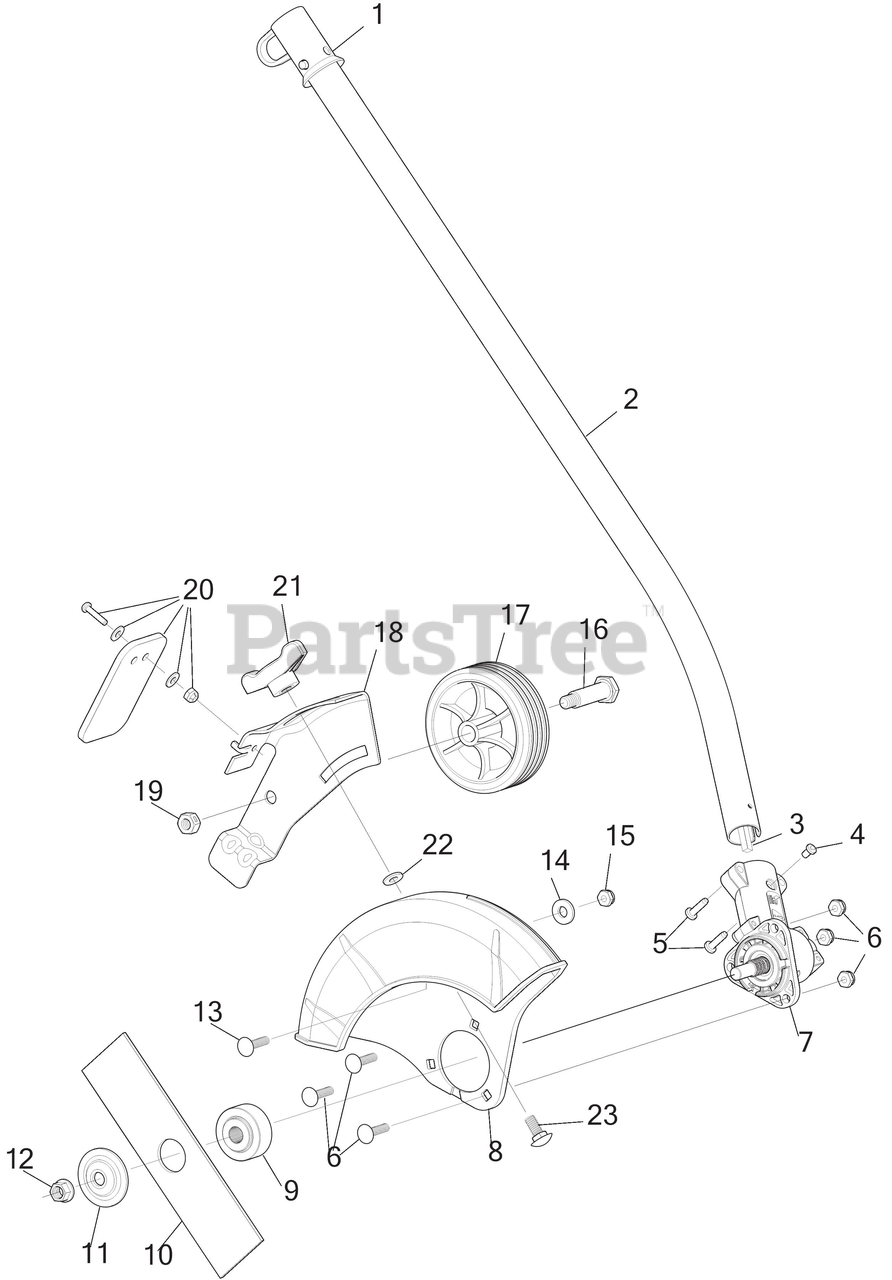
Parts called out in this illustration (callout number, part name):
1	HANGER
2	BOOM ASSEMBLY LE
3	LOWERIBLE DRIVE SHAFT
4	SCREW, 8-32 x .312 P
5	SCREW #
6	HDWR ASM:GUARD MT
7	GRBX ASSEMBLY
9	SPACER:GRBX:BBL
10	EDGER BLADE
11	WASHER-BLADE CLAMP BRUSH CUT
12	BLADE LOCK NUT
13	BOLT:WHEEL MT BRACKET
14	WASH, FLAT .734 OD
15	NUT
16	BOLT
17	WHEEL
18	BRACKET GUARD
19	LOCK NUT 3/8-16
20	DEFLECTOR W/HDW
21	WING KNOB 5/16-18
22	WASHER .406X1.0X.095
23	CARRIAGE BOLT 5/16-18 x .75
